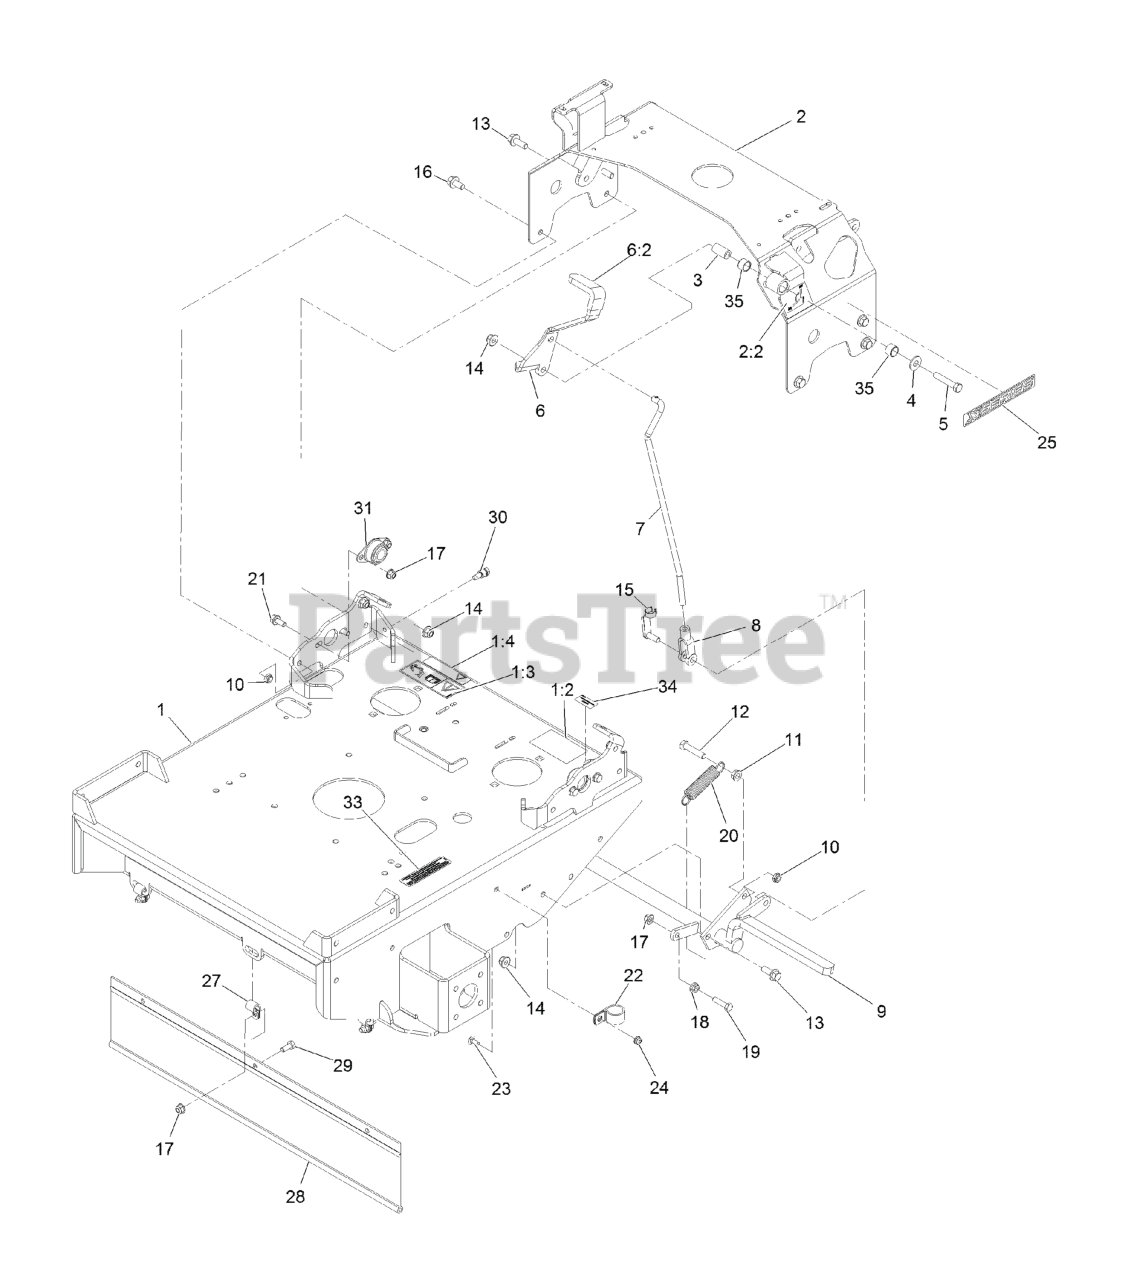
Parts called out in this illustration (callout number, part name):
1	ASM, ENGINE DECK W/ DECAL
1:2	DECAL-WARNING
1:3	DECAL-WARNING, SULKY
1:4	DECAL-DRIVE RELEASE
2	ASM, TANK SUPPORT W/ DECA
2:2	DECAL-PARK BRAKE, CE
3	BUSHING-PIVOT
4	WASHER-FLAT
5	SCREW-HH
6	ASM, BRAKE LEVER W/ GRIP
6:2	GRIP-LEVER
7	LINKAGE-BRAKE
8	YOKE-LINKAGE, BRAKE
9	WLD,BRAKE TTX
11	NUT-HHF, WHIZ
12	SCREW-HH
13	SCREW-HHF 3/8-16 X 1
14	NUT-HF, NI
15	PIN-SPRING, CLEVIS
16	SCREW-HHF
17	NUT-HF, NI
19	SCREW-HH
20	SPRING-IDLER
21	SCREW-HHF
22	CLIP-LOOM
23	SCREW-CARR
25	DECAL-X-SERIES
27	CLIP-LOOM
28	SHIELD,DRAG
29	SCREW-HH
30	BOLT-SHOULDER
31	BEARING-FLANGE, SIDE
33	DECAL-ARRESTOR, SPARK
34	Decal-Patent Ttco.Com
35	SLEEVE-BUSHING
